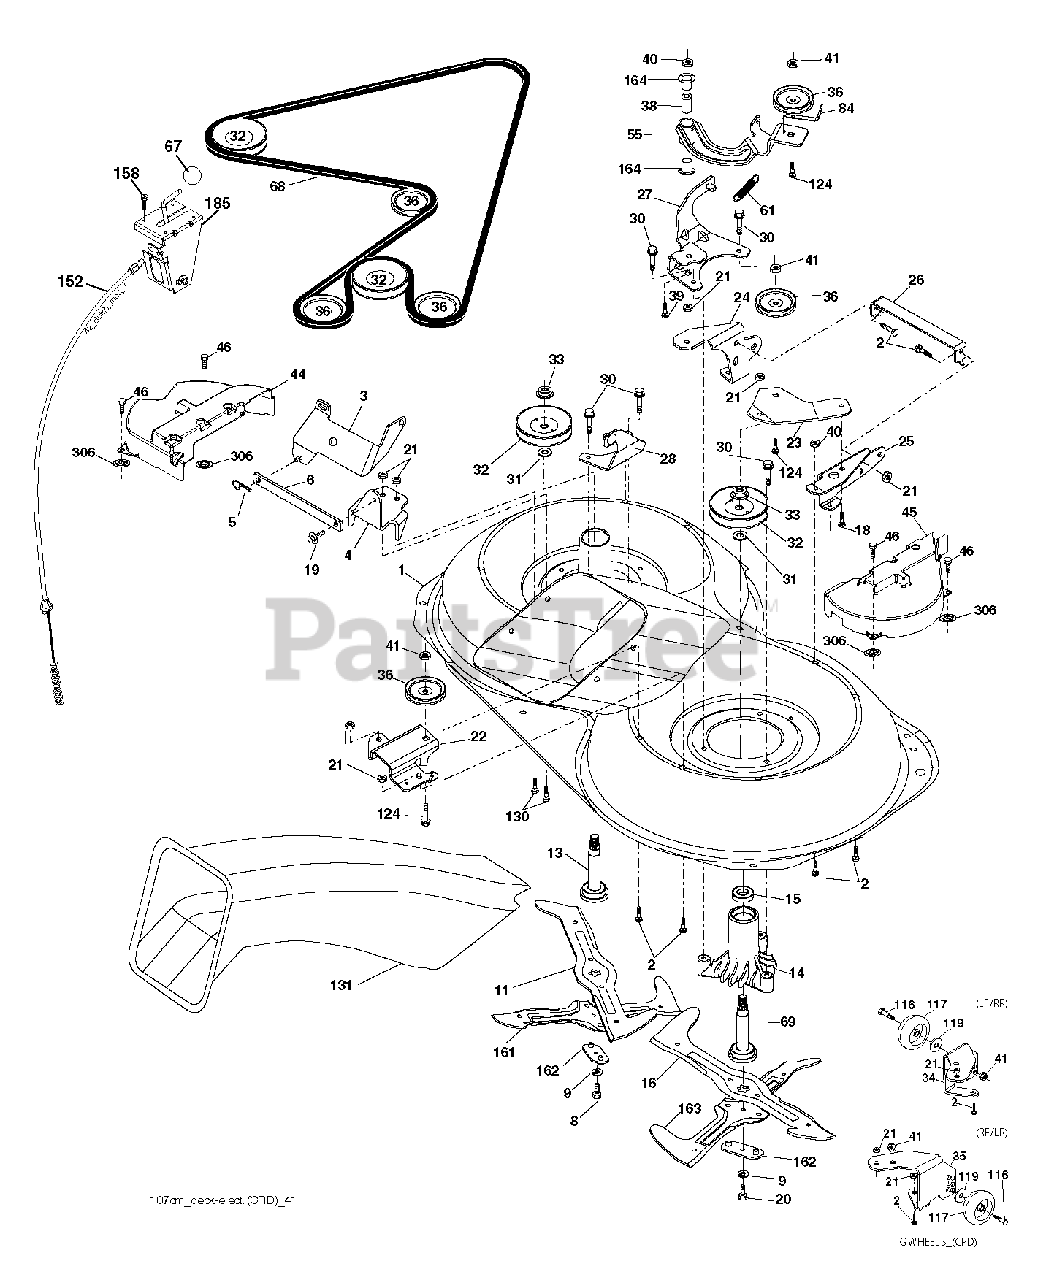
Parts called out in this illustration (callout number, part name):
2	BOLT
3	BRACKET.ASM.BAR.SWAY.CHASS
5	RETAINER-SPRNG RB
6	BAR SWAY
8	Bolt, 3/8-24 X 1.25 Gr8
9	LOCKWASHER
11	BLADE.3N1.LH.CRD
13	SHAFT ASM VENT
16	BLADE.3N1.RH.CRD
19	BOLT SHD 5/16-18
20	BOLT.3/8-24X1.25GR8. LHTHRD
21	LOCKNUT
22	BRACKET
23	BRACKET
27	BRACKET
30	SCREW, WASHER HEAD
31	WASHER.SPACER.MANDREL
33	NUT.FLANGE.LOCK.TOP
36	PULLEY.IDLER.4.25
40	LOCKNUT
41	NUT LOCK FLG 3/8-16 UNC
46	SCREW.1/4-20X5/8
67	KNOB T (3/8 HOLE)
68	HEX-BELT 107 MOWER
69	SHAFT.ASM.W/LWR.BRG.RH.THREAD
84	KEEPER, BELT IDLER
116	BOLT.SHOULDER.3/8-16X3-5/8
117	WHEEL. GUAGE RALLY
124	BOLT.3/8-16X1.50
158	SCREW
162	ADAPTER ADAPTER.CROSS
164	BRNG T
185	HEAD ASM. CABLE CLUTCH
